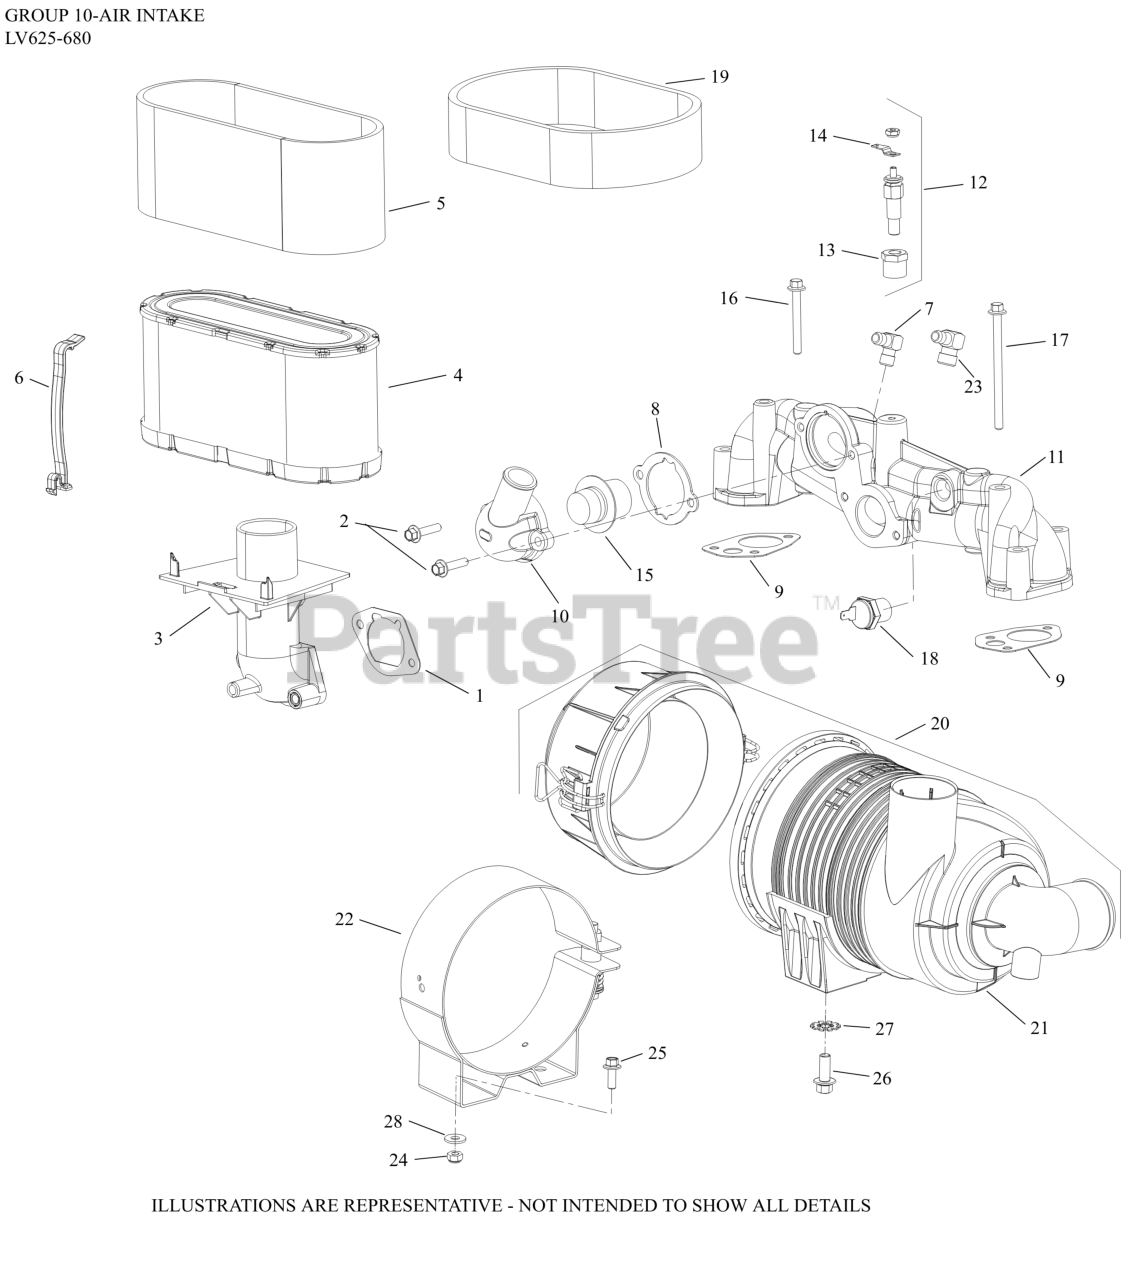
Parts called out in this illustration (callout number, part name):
1	GASKET, AIR CLEANER BASE
2	SCREW, FLG M6X1.0X25
3	ELBOW, AIR INTAKE
4	ELEMENT, AIR FILTER
5	PRE-CLEANER
6	STRAP, RETAINING
7	CONNECTOR
8	GASKET, THERMOSTAT
9	GASKET, INTAKE MANIFOLD
10	HOUSING, THERMOSTAT
11	MANIFOLD, INTAKE-DISCONTINUED
15	KIT, THERMOSTAT - USE 66 453 02-S
16	SCREW, FLG M6X1.0X50
17	SCREW, FLG M6X1.0X90
18	SWITCH, TEMPERATURE AEGIS-DISCONTINUED
